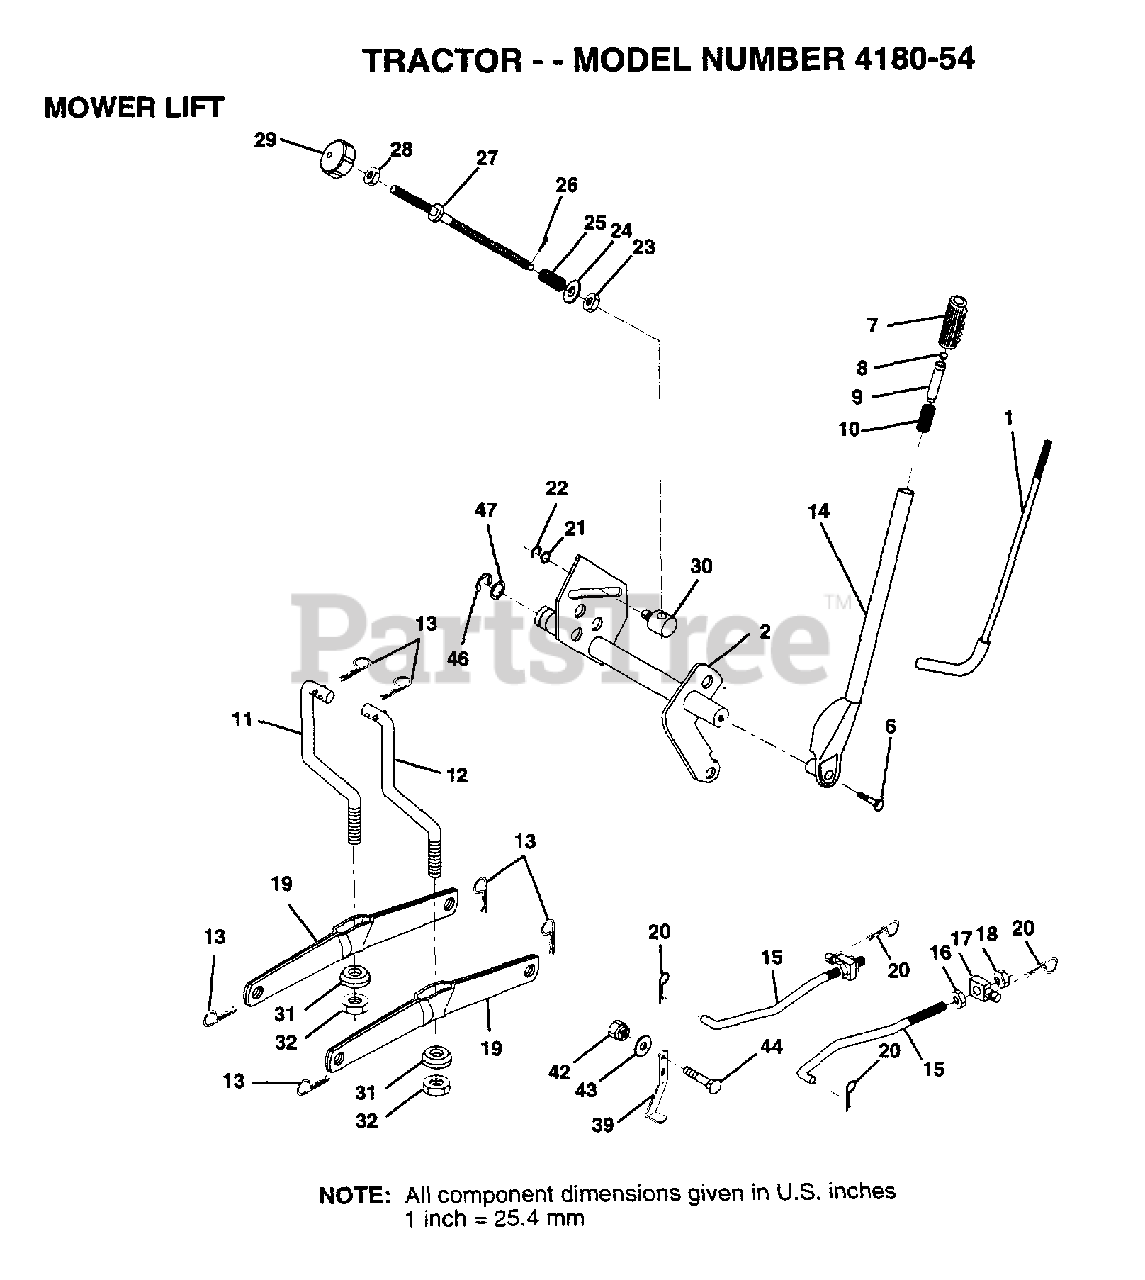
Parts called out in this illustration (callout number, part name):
1	LEVER ROD LT
2	SHAFT LIFT W/IND
6	"BOLT,HEX"
7	GRIP
10	SPRING T
11	LINK.LIFT.LH.GTV
12	LINK.LIFT.RH.GTV.
15	LINK.FRONT
16	NUT
17	TRUNION
18	NUT.LK.W/WSH.1/2.
19	ARM SUSP REAR
20	RETAINER.SPRING
21	WASHER
22	KLIP RING
23	NUT T
24	WASHER
25	SPRING.COMP.INF.H
27	ROD.ADJ.LIFT
28	NUT
29	KNOB INF 3/8-16
30	TRUNION LT
31	BEARING PVT LH
32	NUT.CROWNLOCK.3/8
39	STOP.OVER.CENTER
43	WASHER GT
44	BOLT
46	E-RING
47	WASHER
